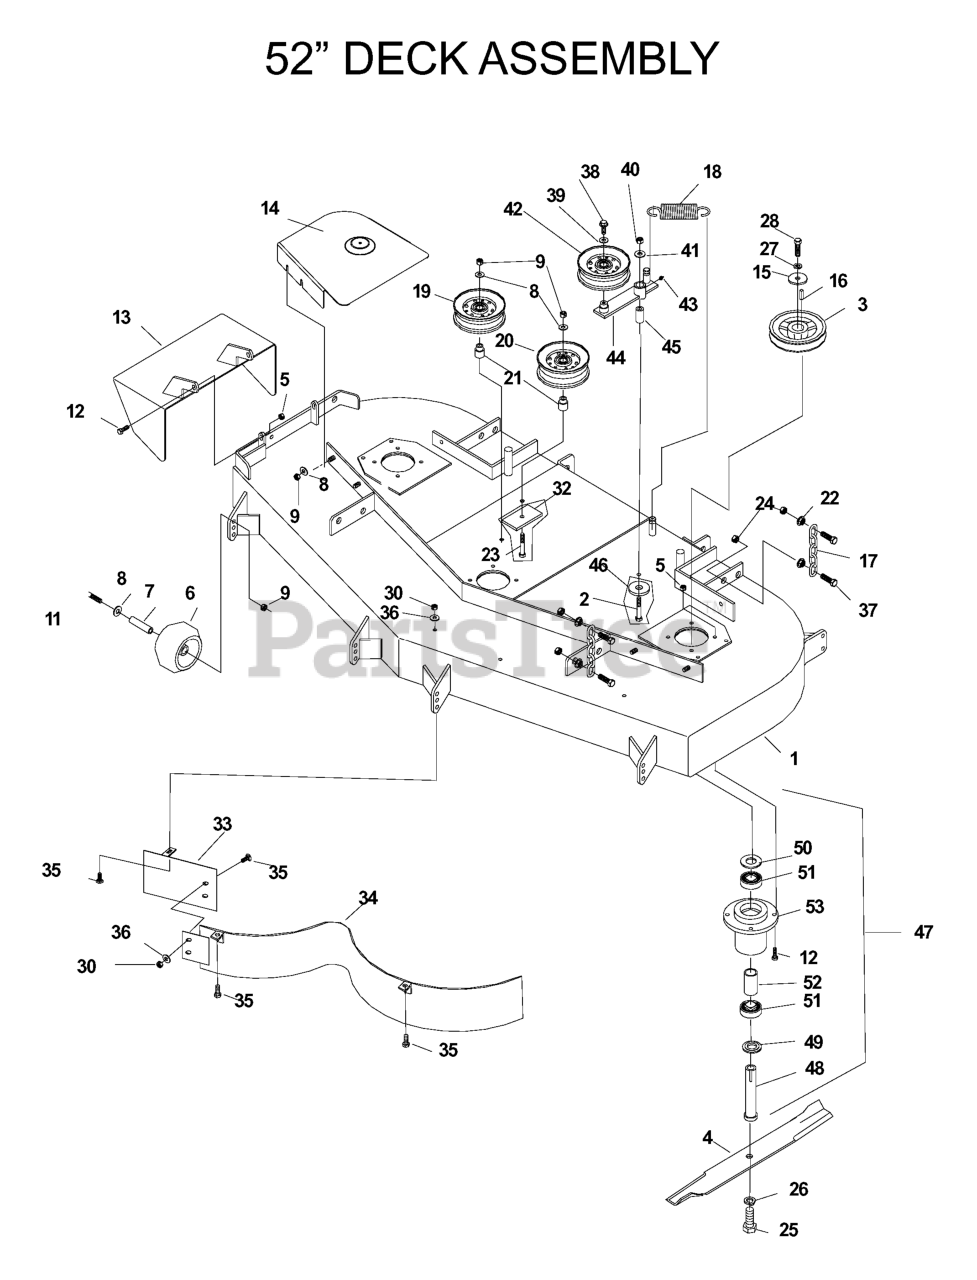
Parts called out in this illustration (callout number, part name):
1	DECK W/DECALS 52" HUS WSL
2	HCS 1/2C X 3 1/4
3	PULLEY 52" DECK
4	BLADE OEM 18"
5	NUT 5/16 NYLOC
6	ANTI-SCALP ROLLER
8	WASHER 3/8 FLAT
9	NUT 3/8-16 NYLOC
10	DECK BELT - 52"
11	HCS 3/8C X 3 1/2
12	HCS 5/16C X 1 1/4
13	DISCHARGE CHUTE ORANGE
14	BELT SHIELD
15	SPINDLE WASHER
16	KEY 1/4 SQ X 1 1/8
17	LIFT CHAIN
18	DECK SPRING
19	IDLER PULLEY
20	IDLER PULLEY (TALL)
21	IDLER BUSHING
22	NUT 7/16C WHIZ
23	SCREW 3/8C X 2 3/4 HEX CAP
24	NUT 7/16C CENTERLOCK
25	HCS 5/8F X 1 1/4
26	LOCKWASHER 5/8
27	WASHER 7/16 LOCK
28	HCS 7/16F X 1 1/2
29	BELT SHIELD
30	NUT 5/16C CENTERLOCK
32	SUPPORT PLATE
33	CENTER BAFFLE - 52"
34	MAIN BAFFLE 52"
35	CARRIAGE BOLT 5/16C X 5/8"
36	WASHER 5/16 FLAT
37	HCS 7/16C X 1 1/2
38	4CS 3/8C X 1 SERRATED HEAD
39	WASHER 3/8 FLAT
40	NUT 1/2-13 HEX NYLOC ZD
41	WASHER 1/2 FLAT
42	IDLER PULLEY
43	ZERK
45	PIVOT BUSHING
46	WASHER, SUPPORT
47	HOUSING ASSEMBLY
49	COMBO SPACER
50	BUSHING.MACHINE.18.GAUGE
51	BEARING
53	HOUSING, DIE CAST
